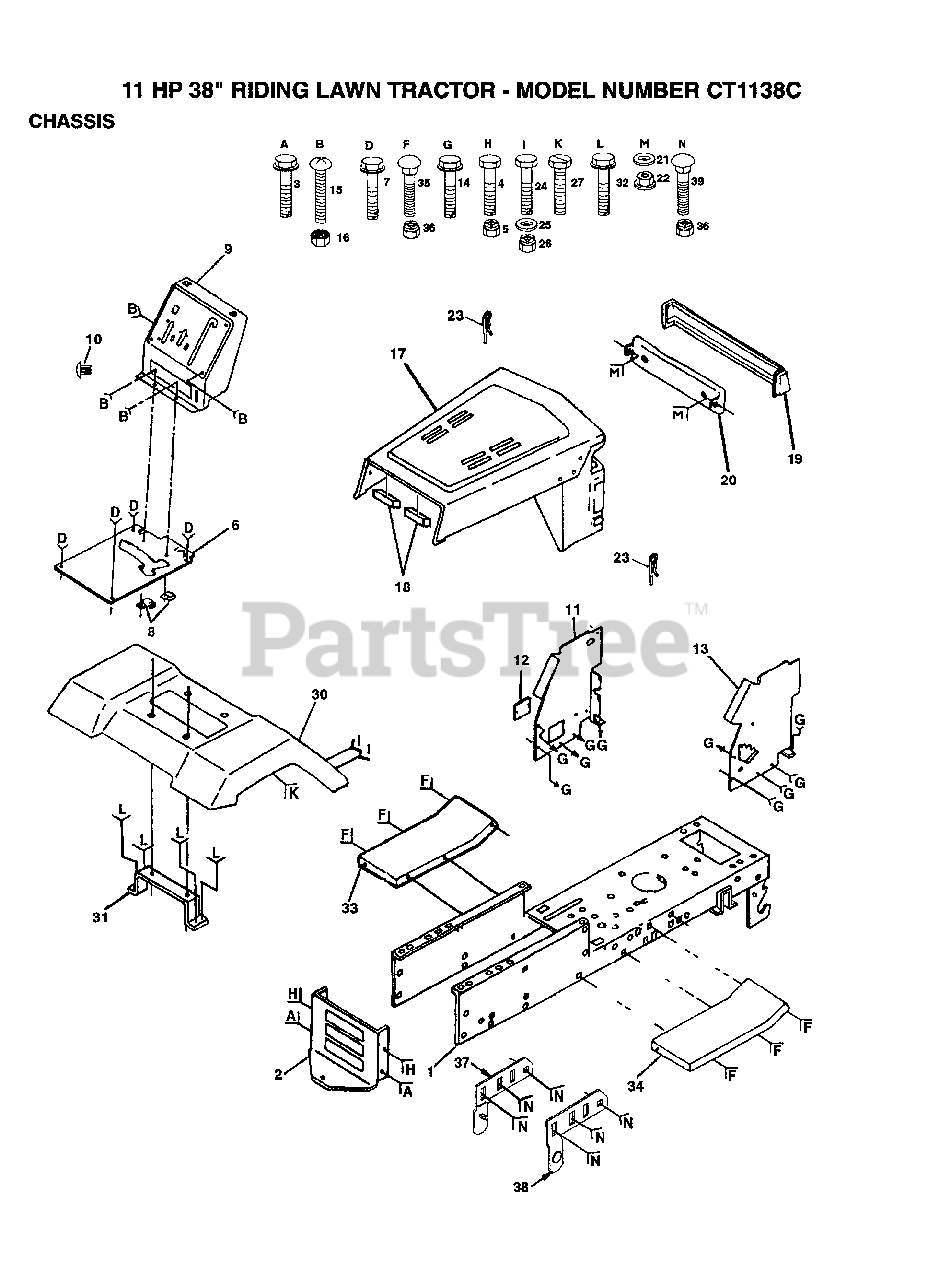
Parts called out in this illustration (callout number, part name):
2	DRAWBAR LT/YT
3	SCREW
7	SCREW LT
8	CLIP T
10	PLUG BUTTON T
11	PANEL DASH LH
12	COVER ACCESS
14	SCREW LT
15	SCREW
17	HOOD/GRILL ASM
19	LENS SERVICE KIT
21	WASHER PM
22	PAL NUT LT
23	SPRING.RETAINER
25	WASHER
27	SCREW LT
32	SCREW
33	FOOTREST LH
34	FOOTREST RH
35	BOLT
37	BRKT ASM PIVOT LH
38	BRKT ASM PIVOT RH
39	BOLT
